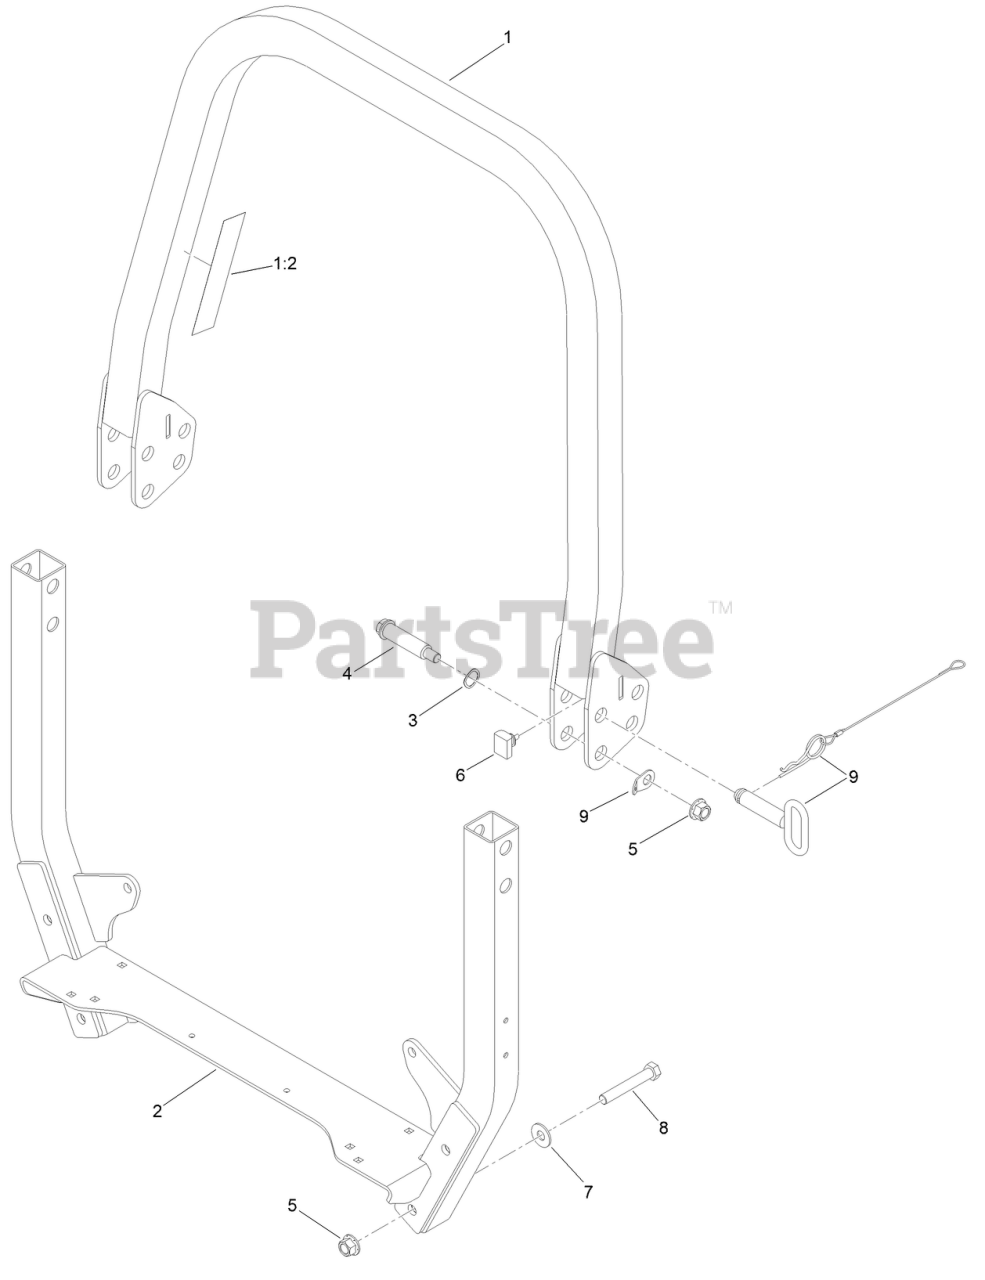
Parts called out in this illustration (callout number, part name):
1	UPPER ROPS ASM
1:2	DECAL-WARNING
2	LOWER ROPS ASM
3	WASHER-WAVE
4	BOLT-SHOULDER
5	NUT-LOCK
6	BUMPER-ROPS
7	WASHER-SPRING
8	SCREW-HH
9	PIN-FOLD, ROPS
